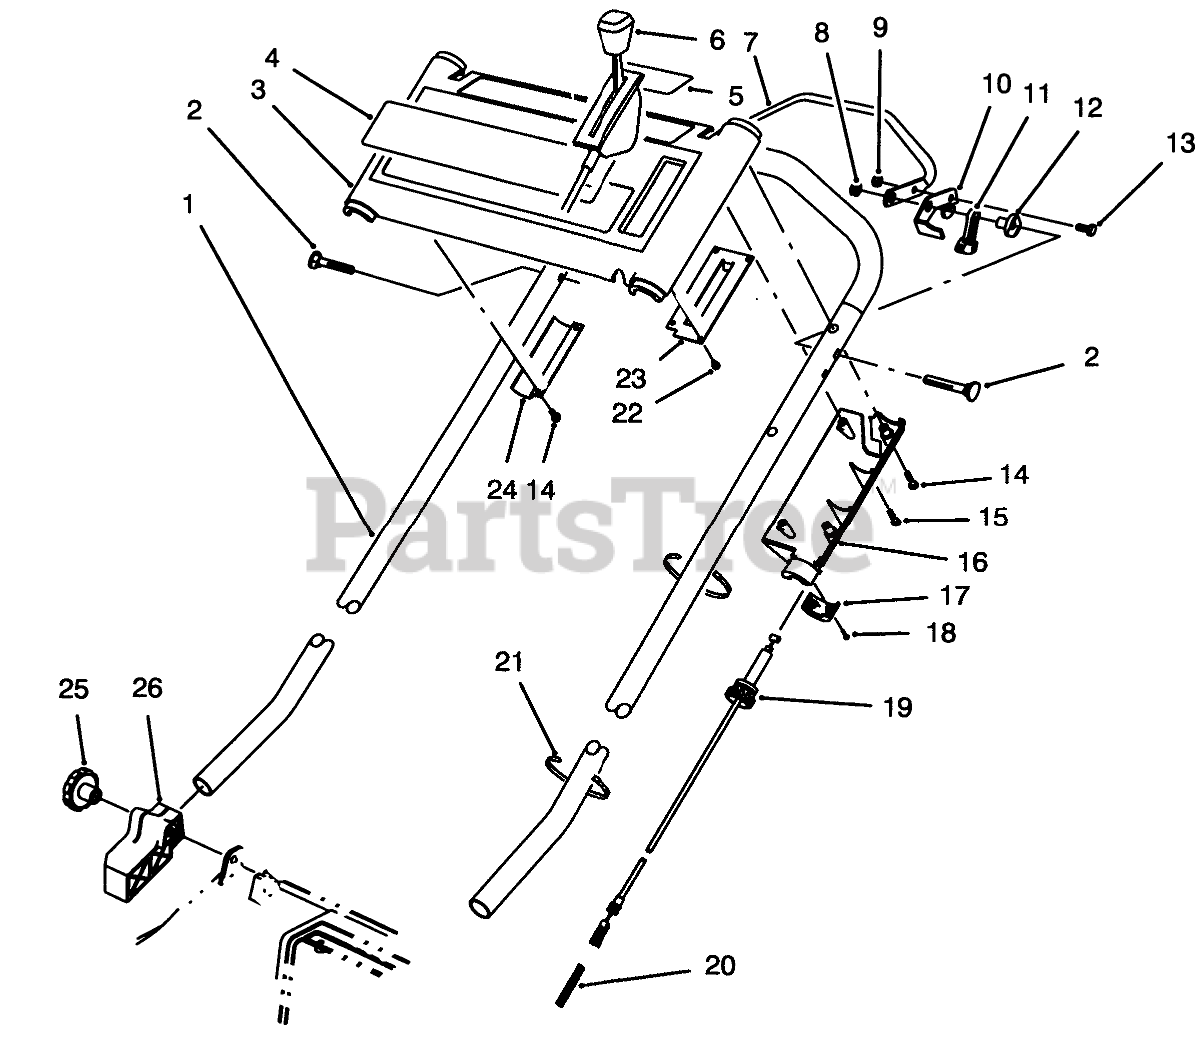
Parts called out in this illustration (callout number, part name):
1	HANDLE (DIPPED)
2	SCREW-HANDLE
3	Panel-Control (Incl. Ref. #4 & 5)
4	DECAL - PANEL 4-CYCLE
5	DECAL - PANEL
6	Control-Throttle Bend Type #1 Sheath Lg. 55.50 Wire Lg. 2 1/2
7	CONTROL BAR
8	NUT-LOCK, NI
9	NUT-LOCK, NI
10	LEVER-CONTROL
11	LEVER-TRACTION
12	SPACER-SUPPORT
13	SCREW-HH
14	SCREW-PPH, PLASTITE
15	Screw
16	Cover-Throttle Lower
17	LOWER THROTTLE CAP
18	#4-14X.62 PLASTITE SCW
19	TRACTION CABLE
20	SPRING-COMPRESSION
21	TIE-CABLE
22	#6-19X.25 PLASK FORM SC
23	THROTTLE PLATE
24	Bracket-Panel
26	MOUNT-HANDLE, RH
